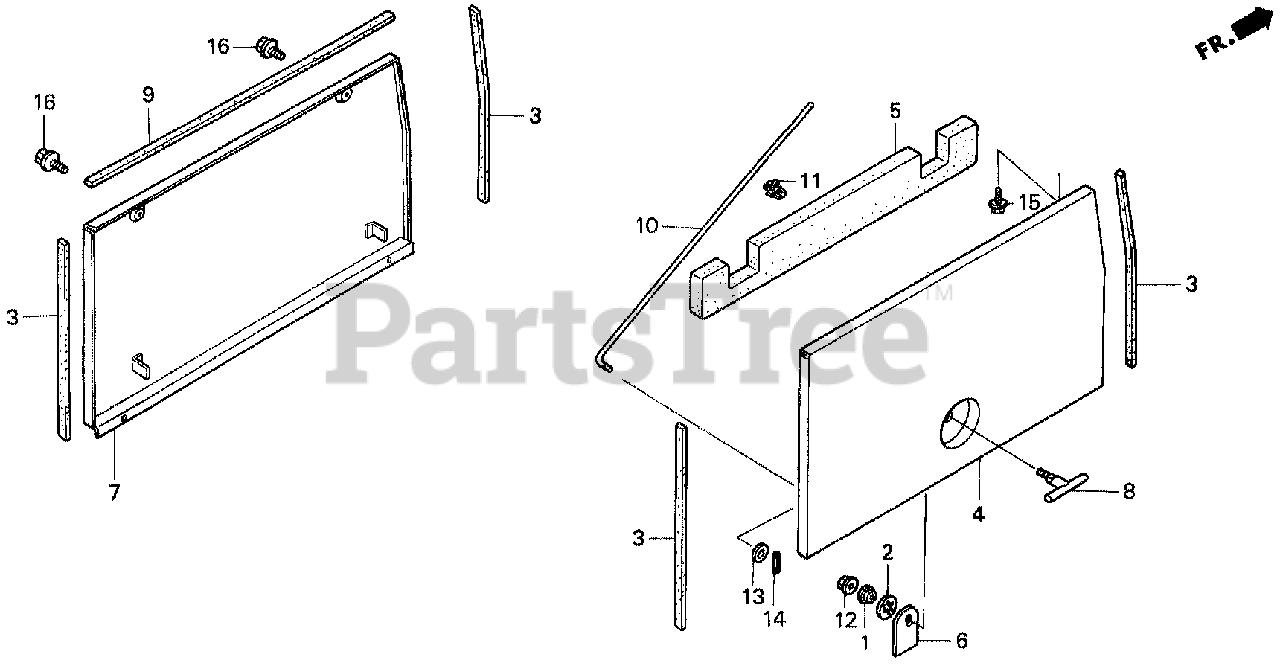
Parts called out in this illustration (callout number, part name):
1	COLLAR, CLUTCH ROD
2	SPRING, ADJUSTING ARM
3	SEAL, COVER (UPPER)
4	COVER, MAINTENANCE *NH213M* (MILD SILVER METALLIC)
5	SEAL, MAINTENANCE COVER
6	PLATE, LOCK
7	COVER, R. SIDE *NH213M* (MILD SILVER METALLIC)
9	RUBBER, SIDE COVER SEAL
10	STICK, MAINTENANCE COVER STOPPER
11	CLIP, ROD HOLDER
12	NUT, FLANGE (8MM)
13	WASHER, PLAIN (10MM)
14	PIN, COTTER (2.0X15)
15	BOLT, FLANGE (6X12)
16	BOLT, FLANGE (8X16)
